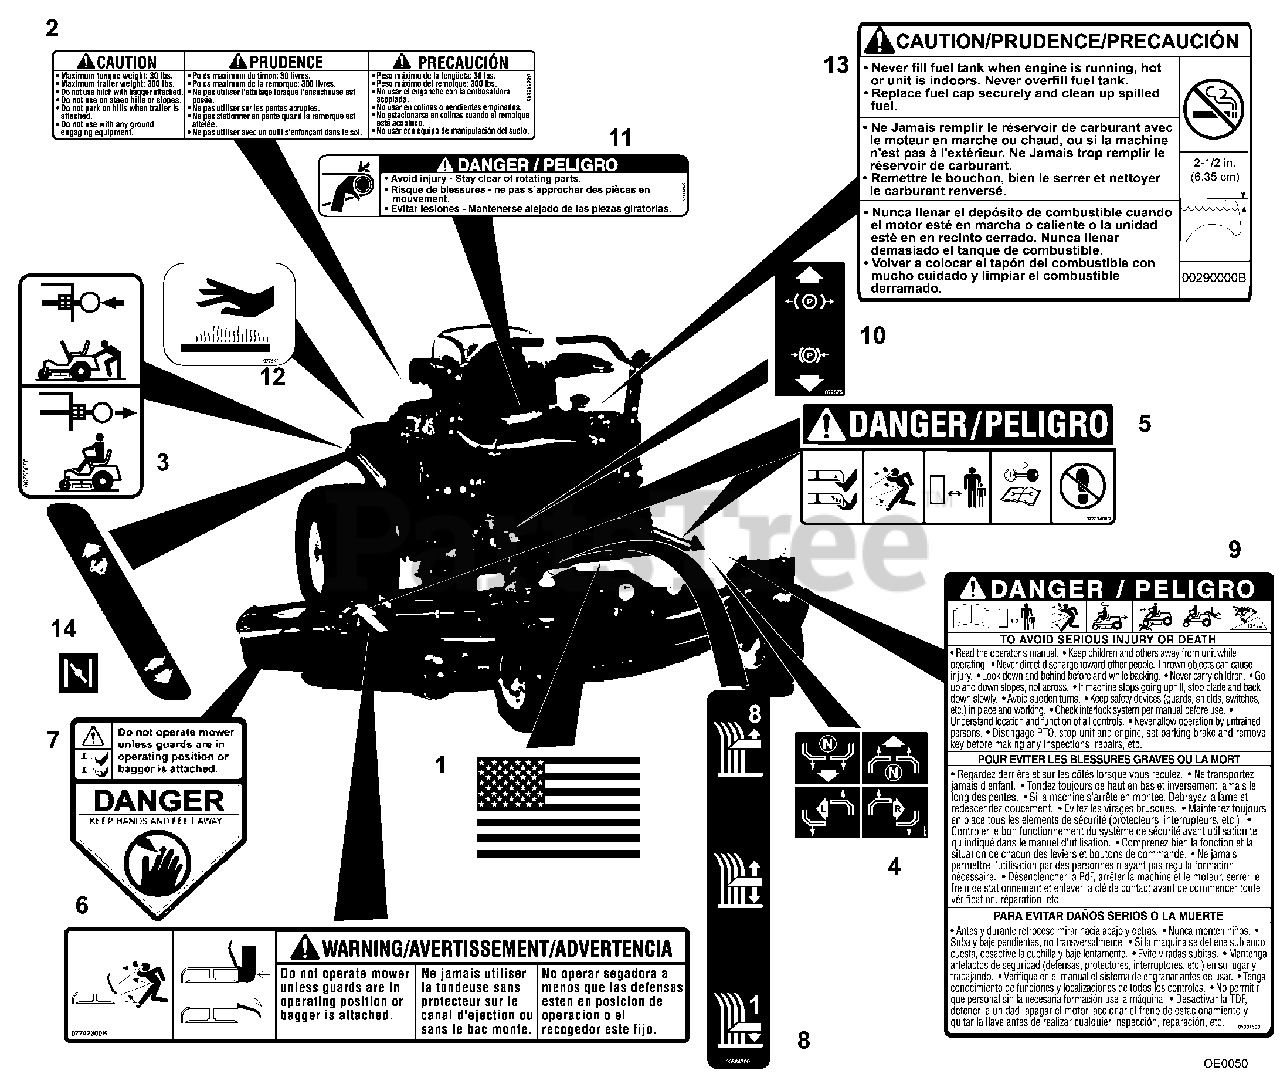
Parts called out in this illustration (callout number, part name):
1	Decal, American Flag
2	Decal, Trailer Hitch
3	Decal, Transmission Disconnect
4	Decal, Instructional Steering
5	Decal, Mower Pan Head Danger
6	Decal, Warning
7	Decal, CPSC Danger
8	Decal, Cut Height
9	Decal, Bilingual Danger
10	Decal, Parking Brake Lever
11	Decal, Danger
12	Decal, Hot Surface
13	Decal, Fuel Warning
14	Decal, Control
